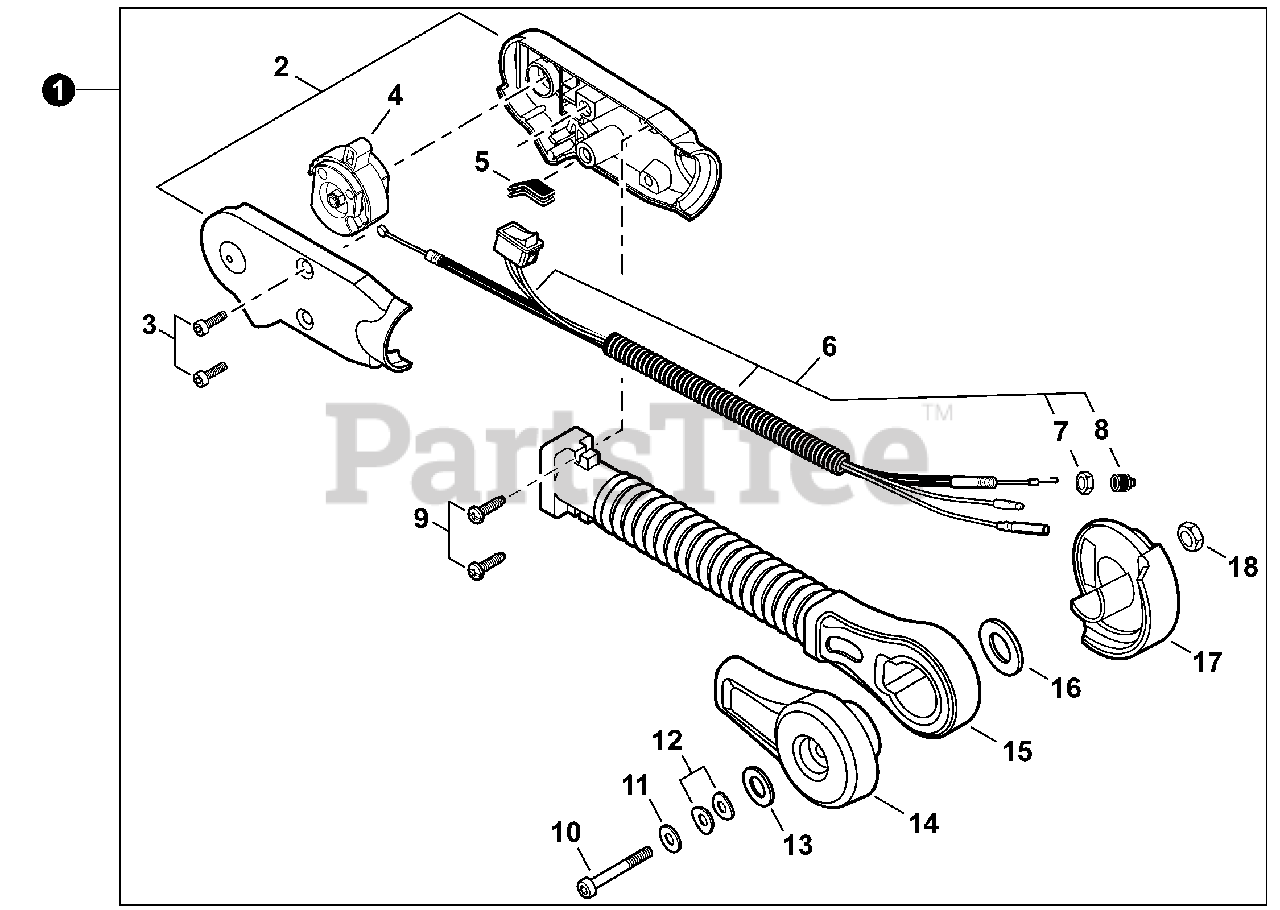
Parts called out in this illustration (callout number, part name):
1	THROTTLE CONTROL KIT - HIP MOUNT
2	GRIP SET, THROTTLE
3	BOLT, TORX 5×16
4	CONTROL, THROTTLE
5	GROMMET
6	CABLE ASSY, CONTROL
7	NUT, HEX M6
8	CAP, DUST
10	BOLT, TORX 6×75
11	WASHER 6.6×20×1.6
12	WASHER, FRICTION 6.6×14.3
13	WASHER 6.5×15.5×0.6
14	BRACKET, ARM - OUTER
15	ARM, THROTTLE CONTROL
16	WASHER 45
17	BRACKET, ARM - INNER
18	NUT, LOCK M6
